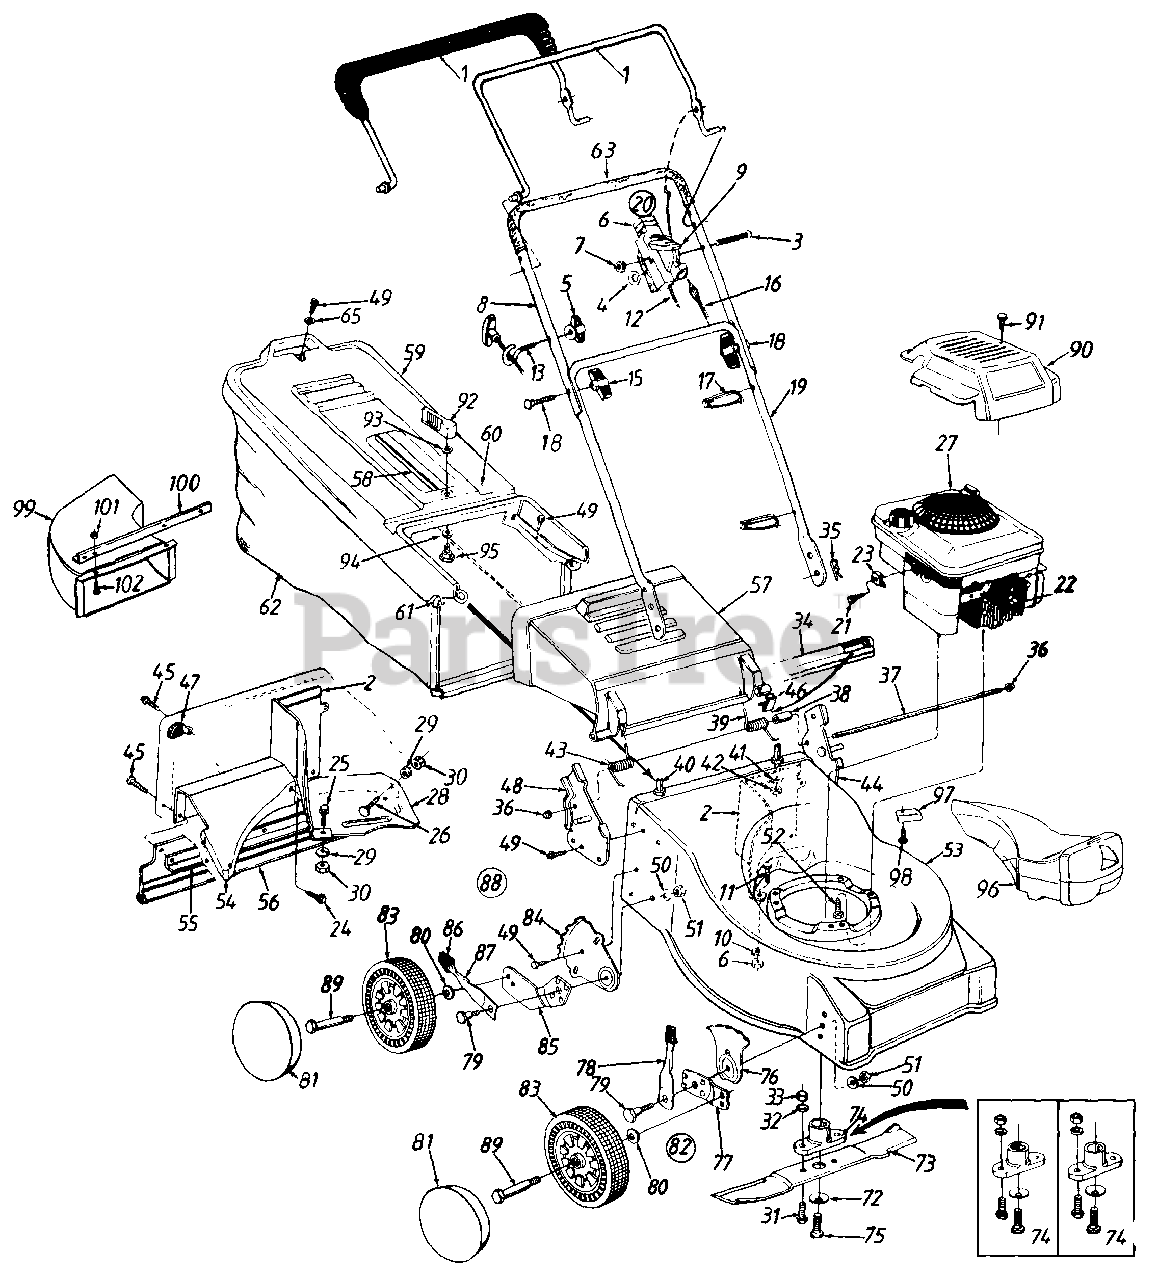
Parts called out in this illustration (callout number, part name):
4	Spr. Wash .66" I.D.
5	Handle Knob 1/4-20 Thd.
6	Throttle Body
7	Hex L-Nut 1/4-20 Thd.
10	Bell-Wash. 1/4" I.D.
11	Hex Bolt 1/4-20 x .85"
12	Throttle Control Wire - 55"
13	Rope Guide
15	Hand Knob
16	Control Cable - 40.5"
17	Cable Tie
18	Curved Hd. Bolt 5/16-18 x 2" Lg.
20	Throttle Box Comp.
21	Hex Self-Tap Scr. #10-32 x .62" Lg.
22	Spark Plug Boot
23	Cable Clamp
24	Hex B-Tap Scr. 1/4 x .38" Lg.
25	Hex Bolt 1/4-20 x .85" Lg.
26	Carriage Bolt 1/4-20 x .5" Lg.
27	Engine
30	Hex Nut 1/4-20 Thd.
31	Hex Bolt 3/8-24 x 1" Lg.
32	L-Wash. 3/8" I.D.
33	Hex Nut 3/8-24 Thd.
34	Seal - Extrusion
35	Int. Cotter Pin 5/16" Dia.
36	Cap Speed Nut
37	Hinge Pin 17.75" Lg.
38	Spacer .255" I.D.
39	Torsion Spring - L.H.
40	Shld. Pin 3/8-24 x 1.43" Lg.
41	L-Wash. 3/8" I.D.
42	Hex Jam Nut 3/8-24 Thd.
43	Torsion Spring - R.H.
46	Deflector Plug
47	Corner Plug
50	Bell-Wash..39" I.D.
51	Hex Nut 3/8-16 Thd.
52	Hex L-Wash. Hd. Scr. 3/8-16 x 1" Lg.
57	Rear Chute Deflector
58	Hardtop Handle
59	Hardtop Bag Cover
60	Rear Catcher Frame
62	Grass Bag
63	Foam Grip
65	Fl-Wash..281" I.D.
72	Bell-Wash..39" I.Q.
73	21" Blade
74	Blade Adapter Kit (Keyed)
75	Hex Bolt 3/8-24 x 1.5" Lg.
76	Height Adj. Plate
78	Spring Lever Ass'y. w/ Knob
79	Shld. Bolt .50" Dia. x .357"
80	Bell-Wash .38" I.D. x .88" O.D.
81	Hub Cap (5-1/2" Dia.
82	Height Adj. Ass'y. Comp.- R.H.
83	Wheel Ass'y. Comp.
84	Index Plate
85	Pivot Bar - R.H.
86	Spring Lever Knob
87	Spring Lever
88	Rear Height Adj. Ass'y. Comp.- R.H.
89	Axle Bolt
90	XTE Black Shroud
91	Hi-Lo Scr. #10 x 1.25" Lg.
92	Grass Catcher Locking Knob
93	Internal L-Wash. 1/4" I.D.
94	Wave Washer 3/8" I.D.
95	Shld. Bolt .342" Dia x .268"
96	Mulching Plug
97	Stop Bracket
98	Hex Tap Scr. 3/8-16 x .75" Lg.
99	Chute Deflector
101	Hex L-Nut 1/4-20 Thd.
102	Mach. Scr. 1/4-20 x .5" Lg
